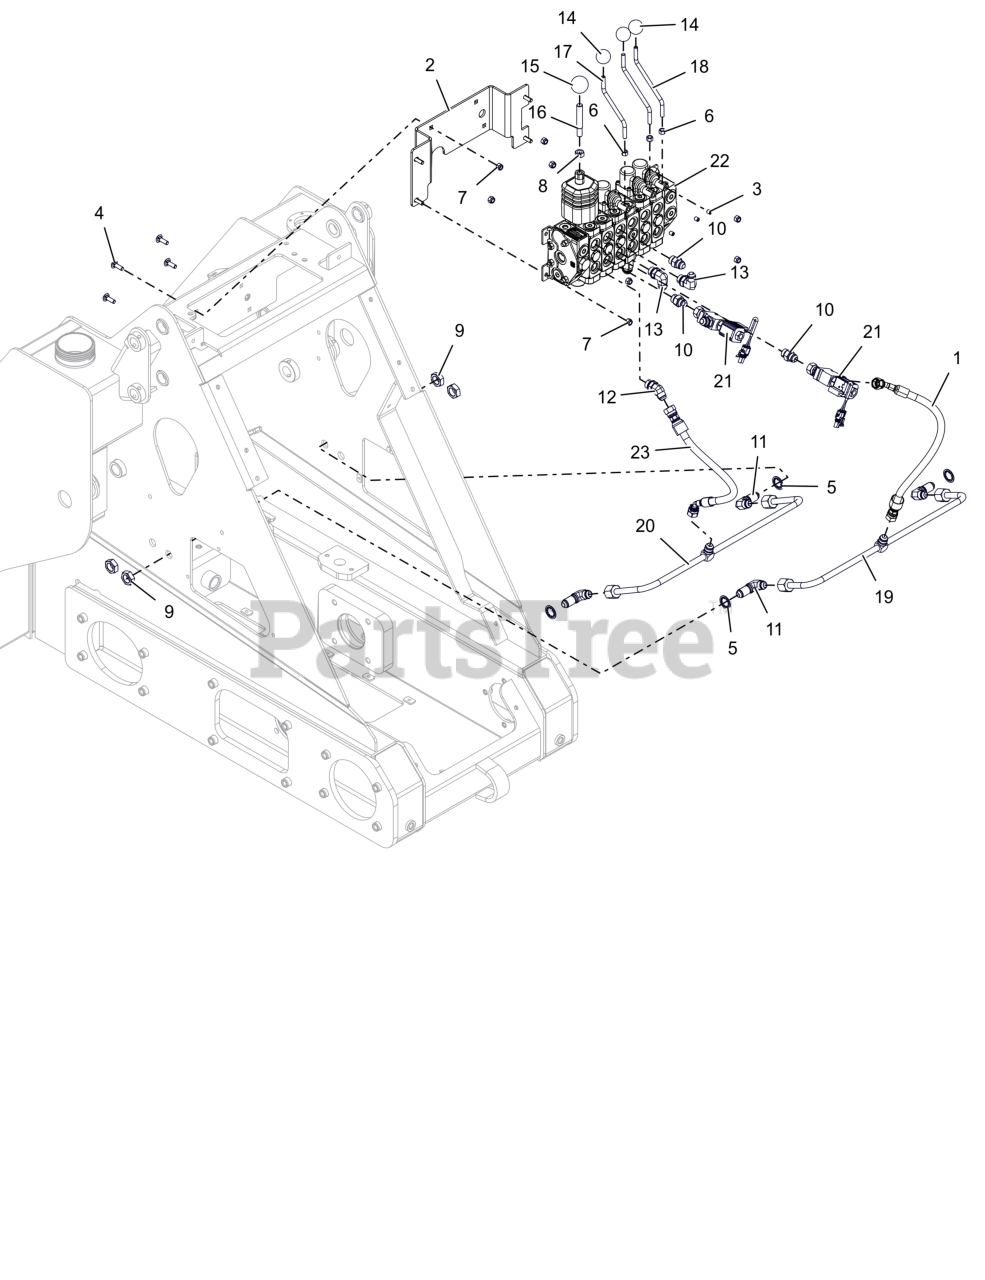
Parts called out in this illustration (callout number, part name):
1	HOSE, HYD .375" X 17.75" LG
2	BRKT, MOUNT - MAIN VALVE (BLACK)
3	SCR-SET, 1.50-6X1.500 CUP
4	BLT,RHSN .31-18X1.00 G5 ZCC
5	WSHR-LK-INT .750 YWZC
6	NUT, HEX M8-1.25 G8.8 ZCC
7	NUT,NYL .31-18 G5 ZCC
8	@NUT-HEX .44-14 YWZC
9	NUT-JAM .75-16 YWZC
10	FITTING, HYDRAULIC 6400 8-8
11	FITTING, HYDRAULIC 2701 8-8
12	FITTING, HYDRAULIC - 6802 8-8
13	FITTING, HYDRAULIC 6801 8-8
14	KNOB, BALL -.312" PRESS ON
15	KNOB, BALL -.500" PRESS ON
16	HANDLE, JOYSTICK
17	LEVER, AUXILIARY
18	LEVER, DRIVE
19	TUBE, HYD - .50" X 25" LOA
20	TUBE, HYD - .50" X .25" LOA
21	VALVE, HYD PORT LOCK
22	VALVE, CONTROL - MAIN
23	HOSE, HYD 45FJIC-8-6 FJIC-8-6 15
